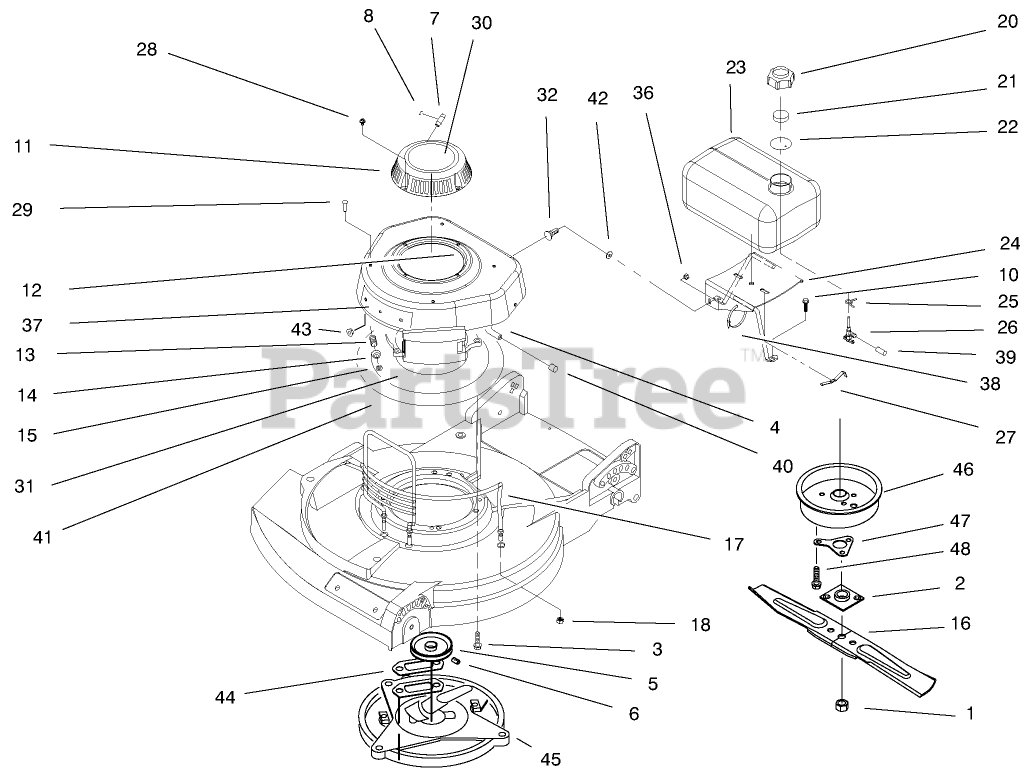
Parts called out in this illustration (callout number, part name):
1	NUT-BLADE
2	PLATE AND COLLAR ASM
3	SCREW-TAPTITE
4	GAS LINE
5	PULLEY F
6	SET SCREW F
7	STOP-ROPE
8	Staple
10	Screw
11	STARTER,SERV S
12	SHROUD AY B S
13	SPRING
14	ACTUATOR-LEVER, BRAKE
15	RETAINER S
16	Blade
17	GUARD - ENGINE
18	NUT-LOCK, NI
20	Cap-Fuel
21	BAFFLE - FOAM SM
22	GASKET S
23	TANK - FUEL
24	Leg & Saddle Assembly
25	CLAMP - HOSE S
26	VALVE&SCREEN SM
27	SPRING
28	SCREW SEMS SM
29	SCREW-SHWH, THREAD FORMING
30	DECAL - RECOIL
31	Engine-2 Cycle
32	SCREW-CARRIAGE
36	LOCKNUT E
37	APPLIQUE S
38	TIE-CABLE
39	CAP PLUG
40	PLUG-CAP
41	PLATE - ENGINE
42	WASHER-FLAT
43	PUSHNUT F
44	GASKET-EXH. VF
45	MUFFLER PLATE F
46	MUFFLER COVER F
47	SUPPORT F
48	SCREW
